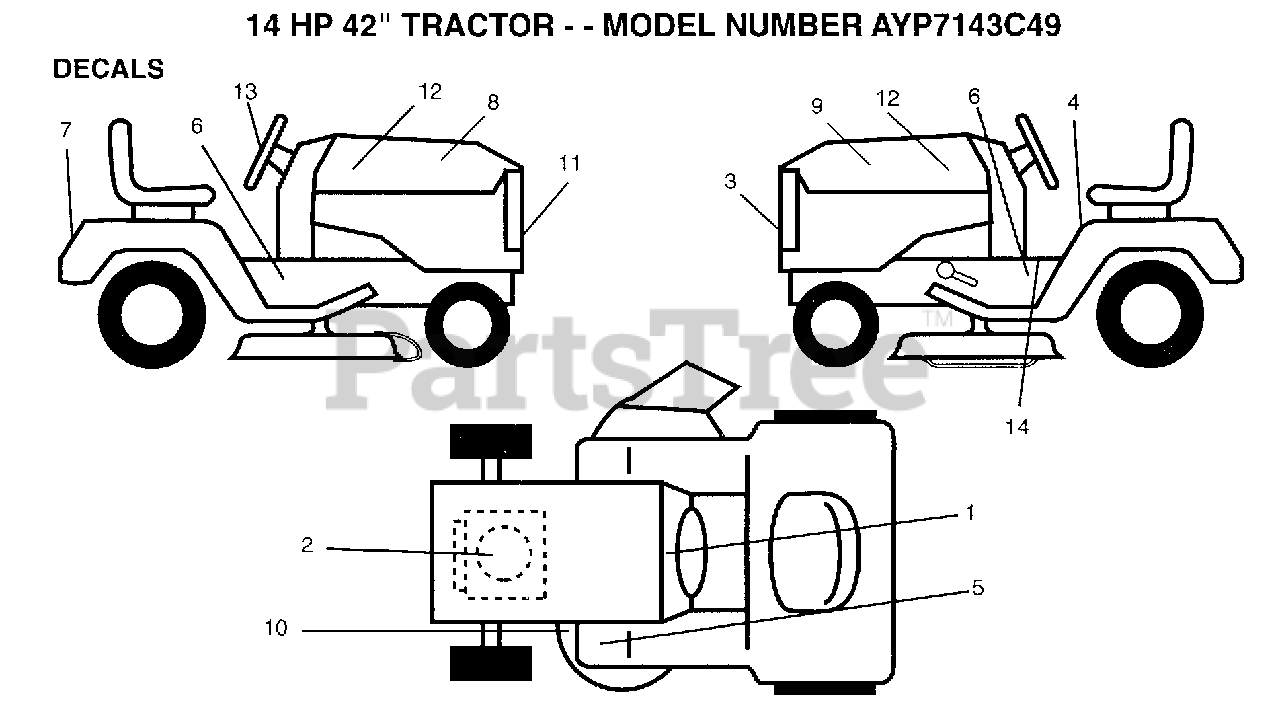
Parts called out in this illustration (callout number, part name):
1	DECAL.DASH.INST.
2	DECAL.ENG.272750
3	DECAL GRILL WIZ
4	DECAL
6	DECAL CHASSIS WIZ
8	DECAL HOOD RH WIZ
9	DECAL HOOD LH WIZ
10	DECAL.V.BELT
11	DECAL GRILL WIZ
12	DECAL HOOD INSERT
14	DECAL BRAK PARK
